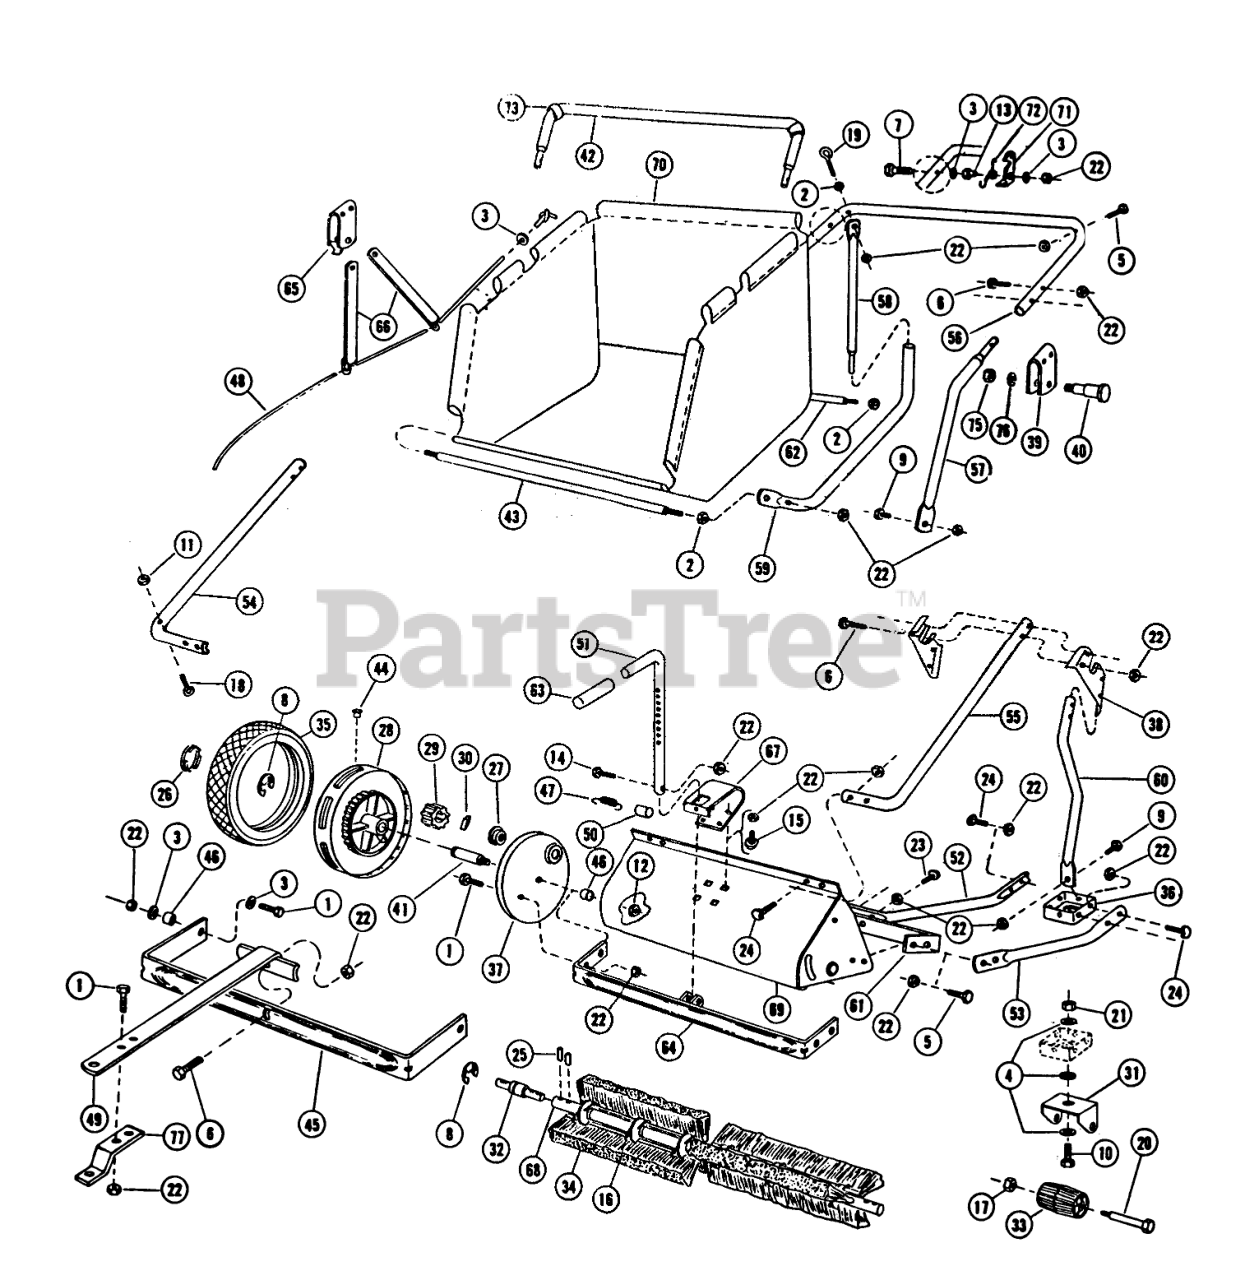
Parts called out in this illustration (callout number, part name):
1	Bolt 5/16-18 x
2	Nut-Nylok
3	Washer
4	Washer-1/2 SAE
5	Bolt 5/16-18 x 1
6	Bolt 5/16-18 x 11/4
7	Bolt 5/16-18 x 1/2
8	RING LAM L 262
9	Bolt Hex 5/16-18
10	Bolt Hex 1/2-13 x 1 1/4
11	Nut-Nylok
12	Locknut 3/8-24
13	Bolt Nut 5/16-18
14	Hex Cap Screw
15	Bolt-Carriage 5/16-18 x 5/8
16	SPRING
17	Locknut 3/8-24
18	Bolt-Eye 1/4-20 x 2
19	Bolt-Eye 5/16-18 x 2 3/4
20	STUD CASTER
21	Locknut-1/2-13
22	Nut-Nylok
23	Bolt-Tube 5/16-18 x 1 1/4
25	Bolt-Hex 1/4-20
25	ROLLPIN 3/16 X 7/8
26	PLUG BUTTON
27	BEARING
28	Wheel Ass-y.
29	PINION GEAR
30	PINION PAWL
31	Bracket-Caster
32	AXLE BRUSH STUD
32	BRUSH STUB AXLE
33	CASTER ROLLER
34	STRIP BRUSH
34	STRIP
35	Tire 10 x 2.25
36	Caster, Plate Ass-y.
37	SHIELD WHEEL
38	Bracket-Frame Pivot
39	Bracket-Hamper Pivot
40	PIVOT PIN
41	WHEEL STUD
42	Tube-Pivot Stand
43	Rod-Hamper Tie
44	Oiler
45	Hitch-U Bar
46	Spacer
47	Spring-Adjustment
48	Dump Rope
49	Tongue-Hitch
50	TUBE SPRING
51	TUBE ADJUSTING
52	Brace-Pivot Stand
53	Brace-Pivot Stand
54	Tube R.H. Support
55	Tube L.H. Support
56	Tube Top Hamper
57	Tube Side Hamper
59	Tube Bottom
60	Support R.H. Pivot
60	Support L.H. Pivot
61	Stiffner-Bar
62	Rod-Rear Hamper
64	Bumper Ass-y.
65	ASSY BRACKET
66	Lever-Dump
67	Bracket-Adjustment
68	Axle-Brush
68	ASSY BRUSH AXLE & DS
69	Shield-Ass-y.
70	Hamper-Ass-y.
70	HAMPER ASSY
71	Latch-Hamper
72	Spring-Latch
73	Sleeve-Rubber
74	Hex Cap Screw 5/16-18 x 4
75	Locknut 3/8-24
76	Lockwasher
77	BRACKET-HITCH PIN
